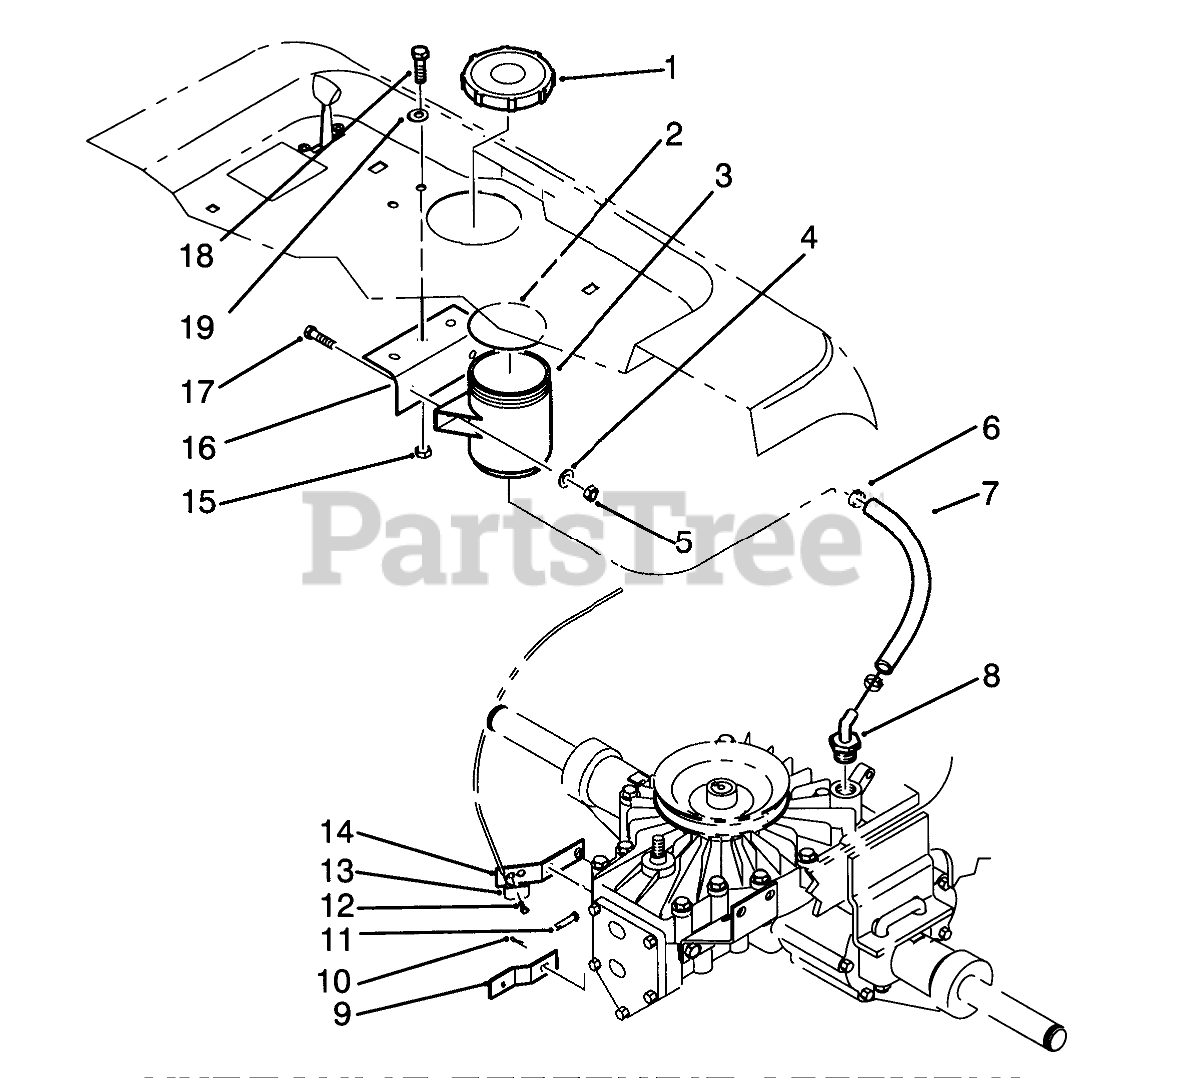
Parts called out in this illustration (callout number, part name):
1	ASS'Y-RESERVOIR
2	COVER GASKET
3	RESERVOIR
4	WASHER-FLAT
5	NUT-LOCK, NI
6	CLAMP .875
7	HOSE-7"
8	HOSE BARB
9	Plate
10	Cotter Pin
12	Screw
13	CLAMP THROTTLE
14	PLATE-MTG
15	NUT-LOCK, NI
16	BRACKET R
17	SCREW-HH
18	SCREW-HH
19	WASHER-PLAIN
